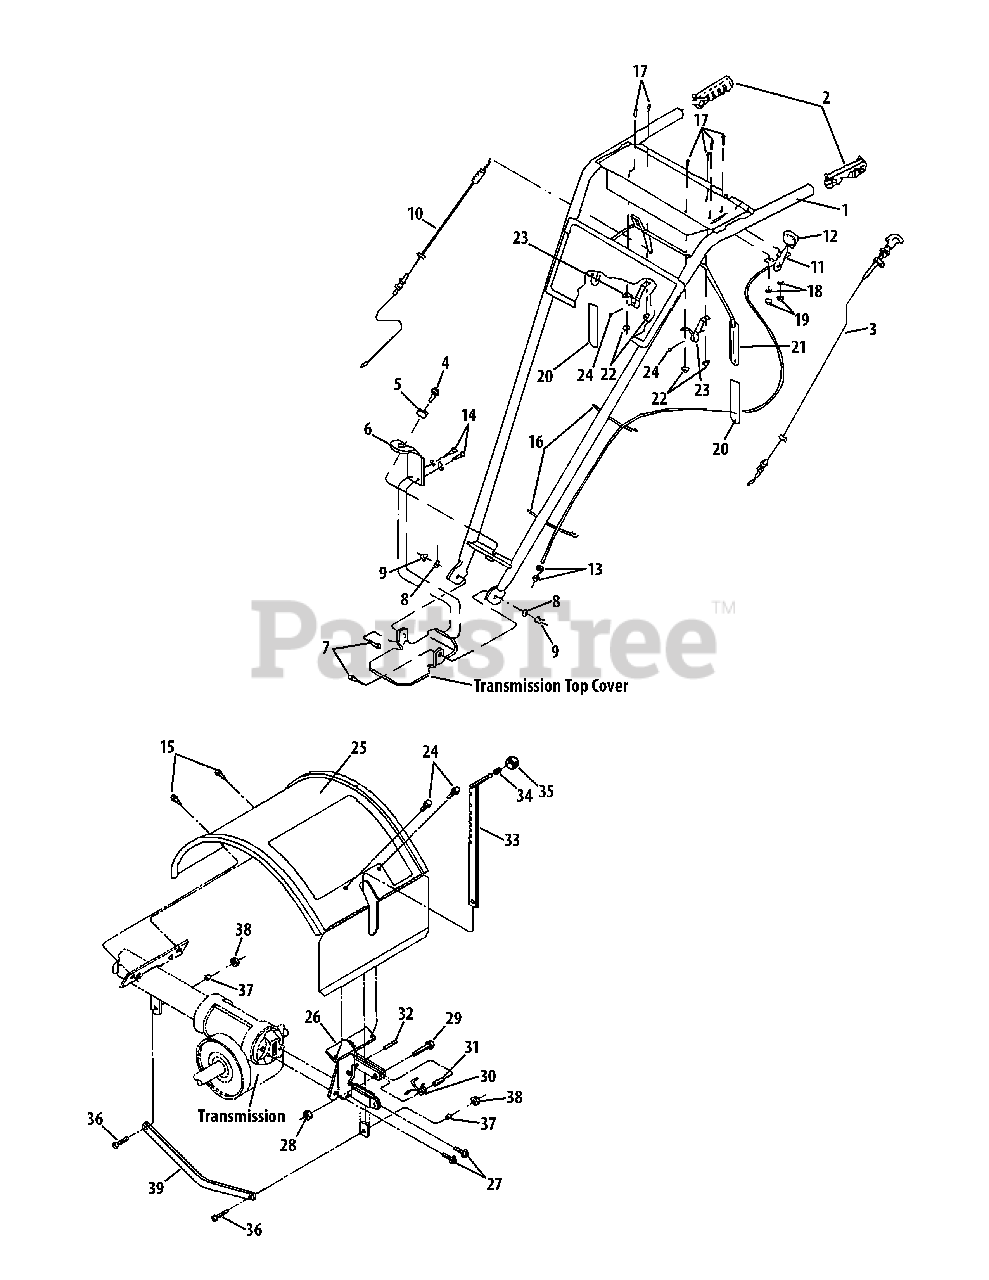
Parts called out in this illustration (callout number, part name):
1	Handlebars
3	Reverse Clutch Control Cable
4	Hex Flange Screw, 3/8-16
5	Keyed Washer
6	Handlebar Hgt. Adjustment Bracket
7	Hex Hd. Screw, 3.8-16 x 1
8	Plain Washer, 3.8
9	Hex Locknut, 3.8-16
10	Forward Clutch Control Cable
11	Wheel Gear Control & Cable Ass.
12	Wheel Gear Control Lever Knob
13	Hex Nut, 5.16-24
14	Hex Head Screw, 3.8-16 x 5/8
15	Self-tapping Screw, 5.16-18 x 5.8
16	Cable Ties
17	Round Head Screw, #10-32 x 1.2
18	Lockwasher, #10
19	Hex Nut, #10-32
21	Forward Clutch Bail
23	Bail Support Bracket
24	Self-tapping Screw, 1.4-20 x 1.2
26	Depth Regulator
27	Hex Flange Screw, 5.16-18 x 5.8
28	Hex Locknut, 1.4-20
29	Hex Head Screw, 1.4-20 x 1
32	Roll Pin (spiral), 1.4 x 1
33	Depth Regulator
34	Retaining Ring
35	Depth Regulator Knob
36	Hex Head Screw, 3.8-16 x 1-1.4
37	Drag Bar Bushing
38	Hex Nut, 3.8-16
